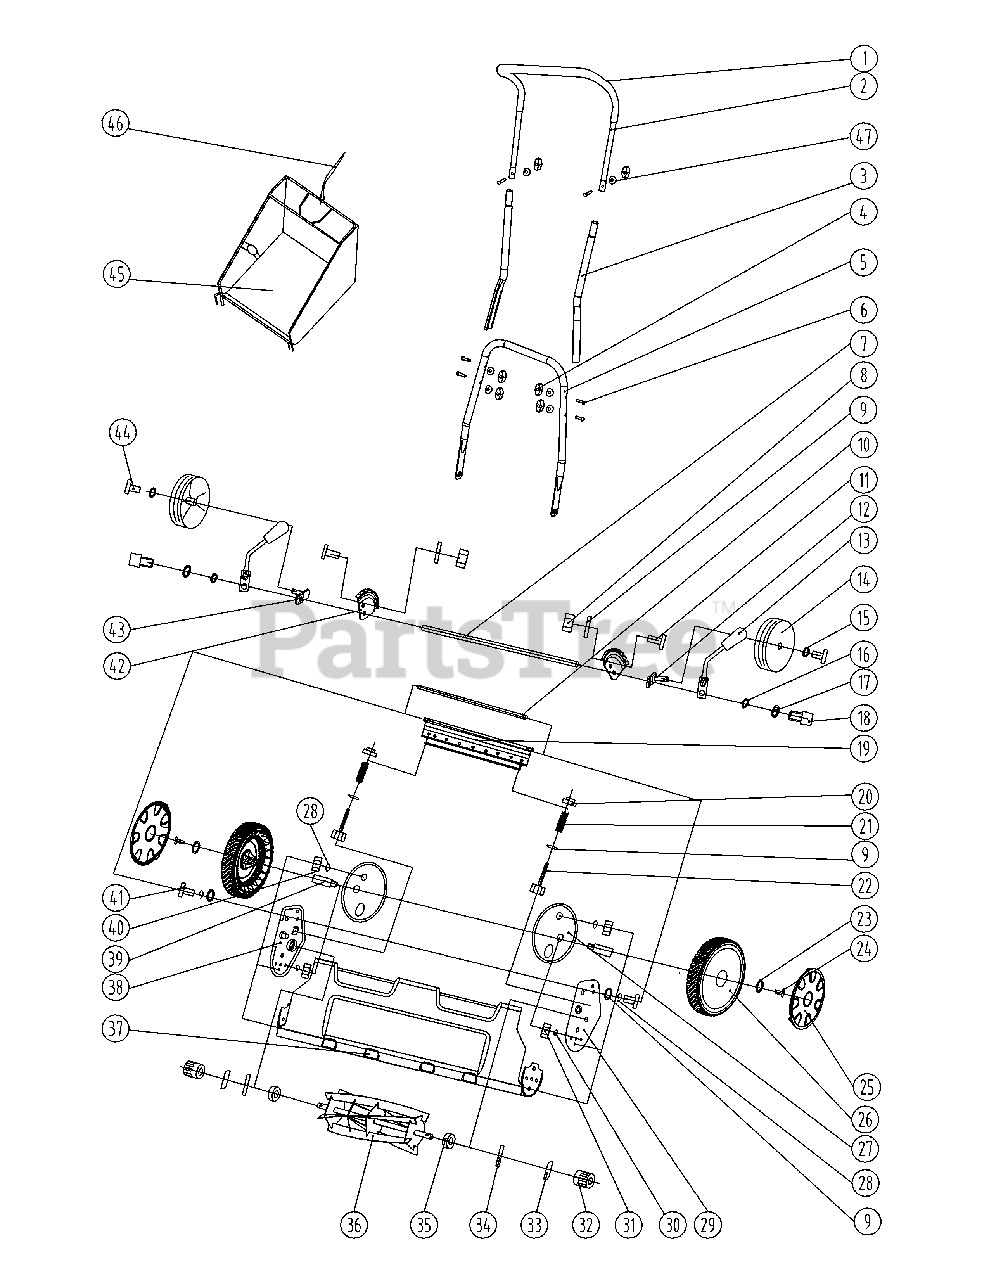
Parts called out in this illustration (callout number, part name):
2	UPPER HANDLE
3	MIDDLE HANDLE
5	LOWER HANDLE
7	REAR SHAFT
10	PIN
12	REAR BRACKET (LH)
13	HANDLE ADJUSTMENT (RH) RED
13	HANDLE ADJUSTMENT (LH) RED
14	REAR WHEEL
19	LOWER BLADE BRACKET
22	BOLT-M8 x 1.65
26	COMPLETE WHEEL
29	SUPPORT BRACKET (LH)
32	GEAR-41MM
36	ROLLER BLADE
37	DEFLECTOR SHIELD
38	SUPPORT BRACKET (RH)
39	WHEEL AXLE
42	ADJUST BRACKET (RH)
42	ADJUSTMENT BRACKET 9T (LH)
43	REAR BRACKET (RH)
45	GRASSBAG
46	GRASSBAG STRAP
47	SADDLE WASHER
